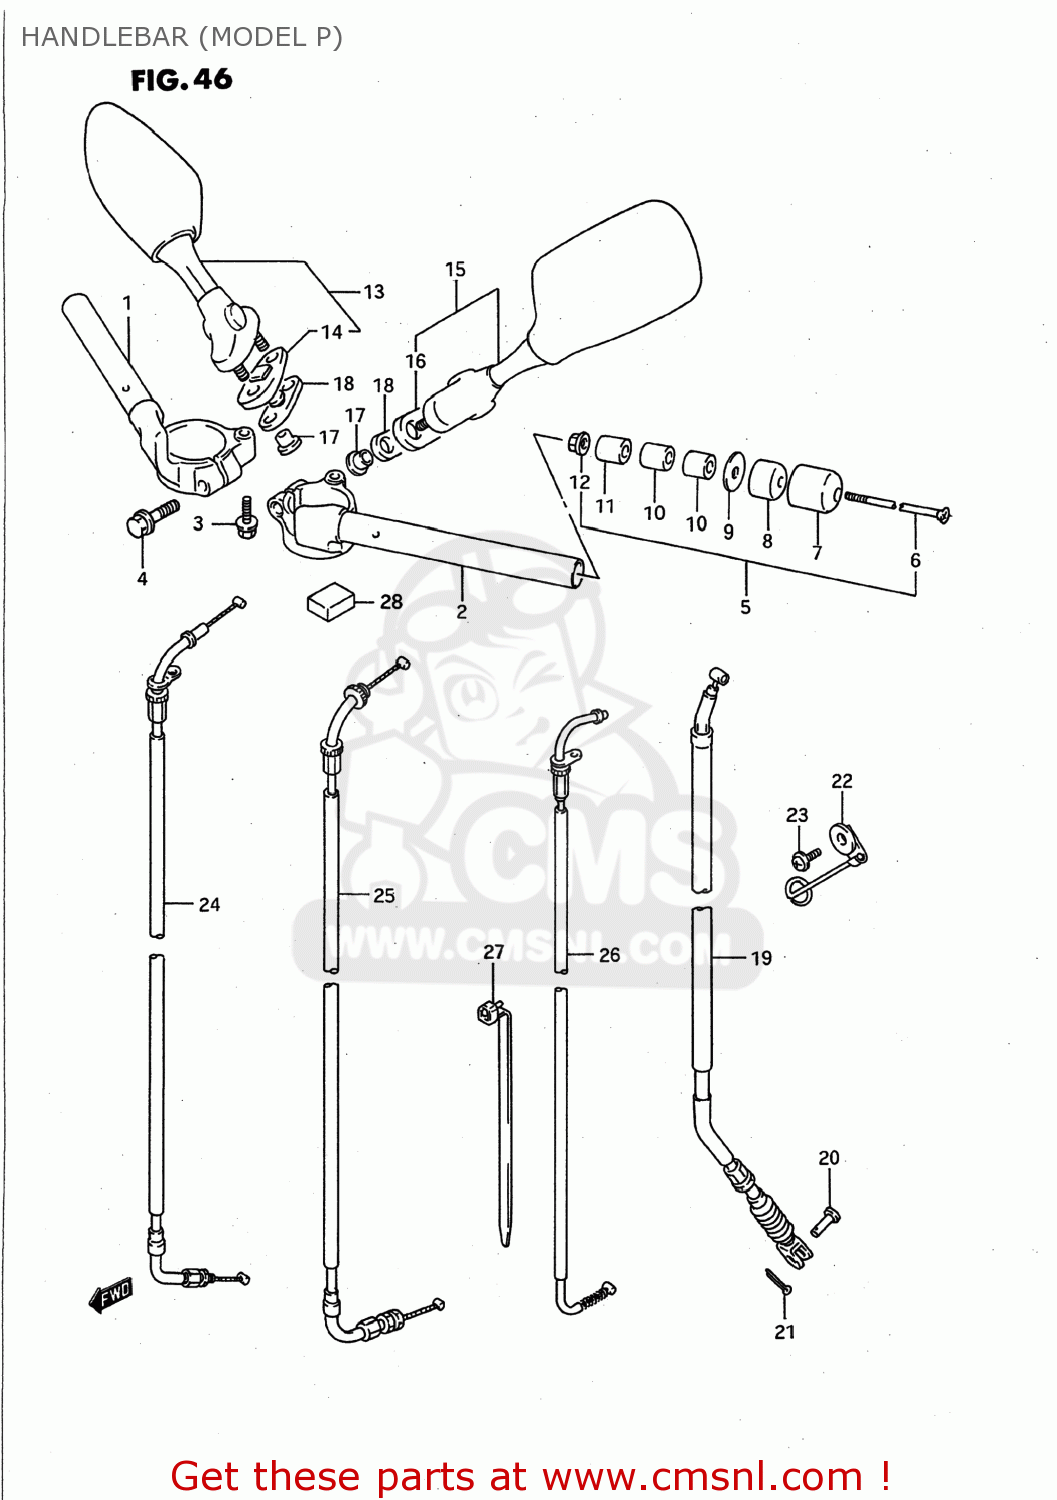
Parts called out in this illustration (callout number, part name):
1	HANDLEBAR,RIGHT
2	HANDLEBAR,LEFT
3	BOLT 6X20
4	BOLT
5	BALANCER SET,HANDLEBAR
6	SCREW(6X110)
7	CAP,BALANCER
8	BALANCER,HANDLE
9	SPACER,BALANCER
10	BALANCER,HANDLEBAR INNER
11	EXPANDER,HANDLE BALANCER
12	NUT
13	MIRROR ASSY,RR VIEW,R
14	GASKET,RR VIEW MIRROR,R (NAS)
15	MIRROR ASSY,RR VIEW,L
16	GASKET,RR VIEW MIRROR,L (NAS)
17	NUT,RR VIEW MIRROR
18	CUSHION,RR VIEW MIRRORR
19	CABLE ASSY,CLUTCH
20	PIN(L:15)
21	PIN
22	GUIDE,DRAIN HOSE
23	SCREW
24	CABLE ASSY,THROTTLE NO.1
25	CABLE ASSY,THROTTLE NO.2
26	CABLE,STARTER
27	CLAMP(L:235)
28	CUSHION,FRAME COVER
